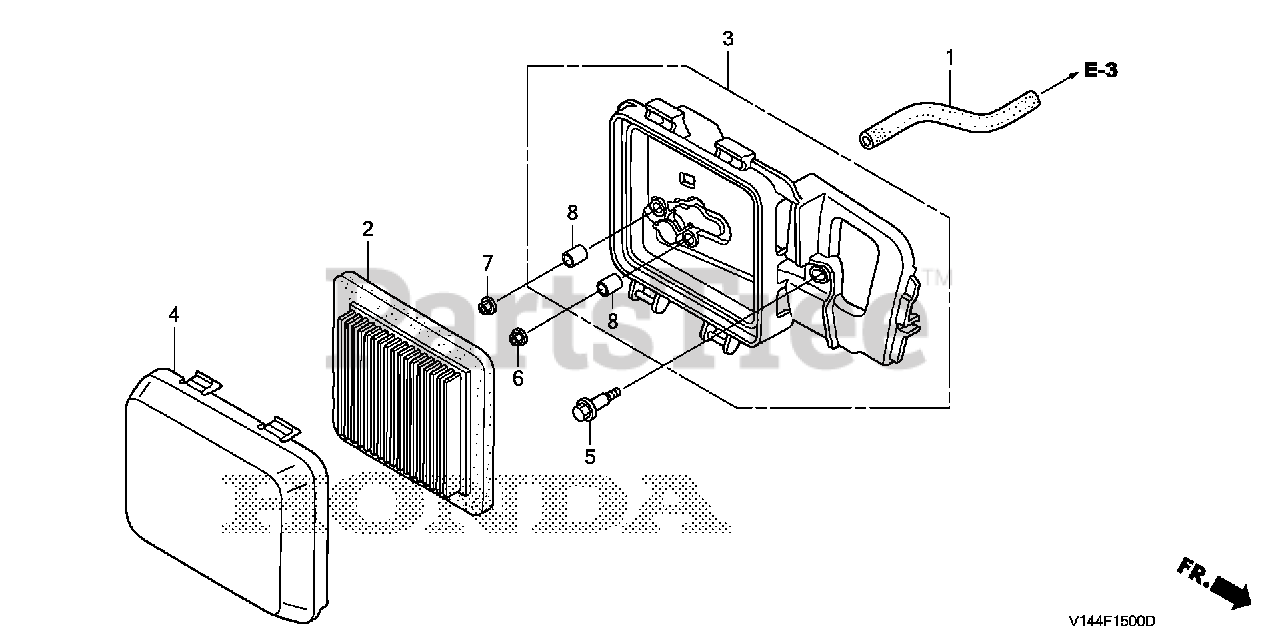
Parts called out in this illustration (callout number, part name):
1	TUBE, BREATHER
2	ELEMENT, AIR CLEANER (TOYO ROKI) (ENGINE NO.)
3	HOUSING, AIR CLEANER
4	COVER, AIR CLEANER
5	BOLT, FLANGE (5X20)
6	NUT, FLANGE (5MM)
7	NUT, FLANGE (5MM)
8	COLLAR, AIR CLEANER
